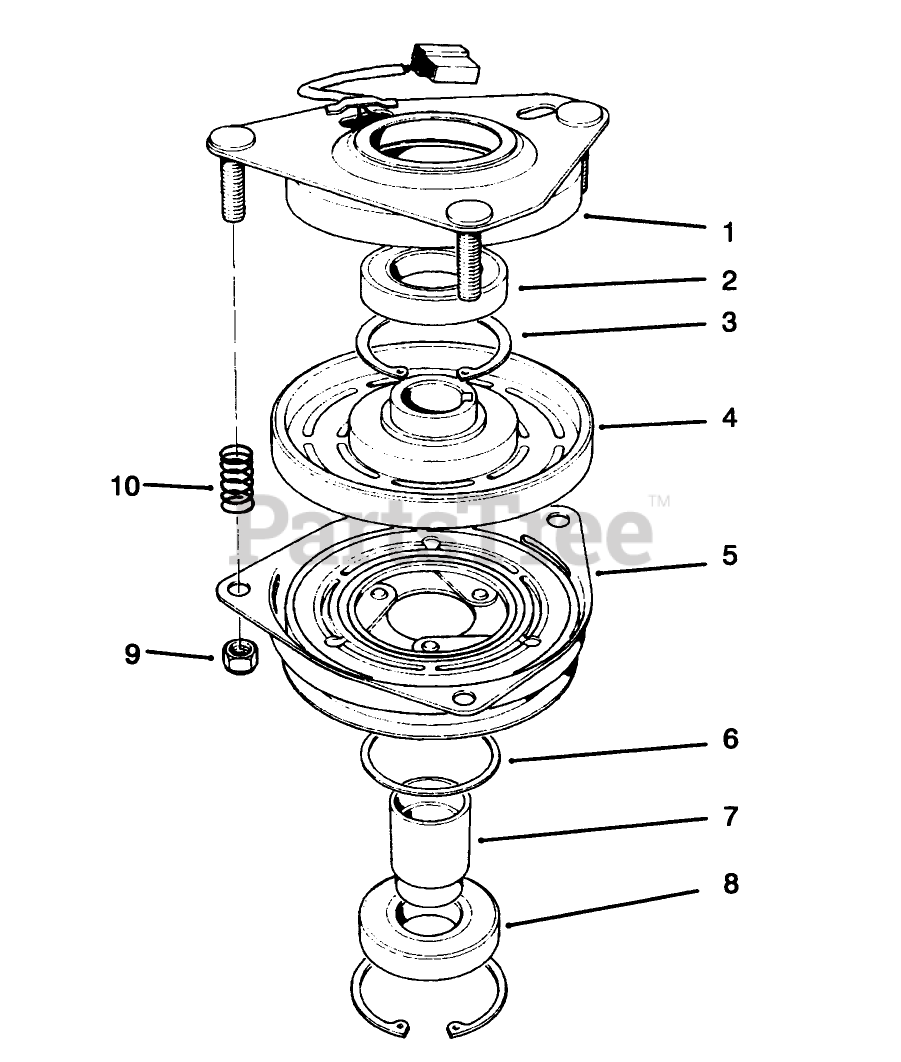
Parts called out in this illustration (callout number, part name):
1	FIELD BEARING ASM
2	BEARING-FIELD
3	RING-RETAINING
4	FIELD COIL/ROTOR BEARING ASM
6	SPACER-BEARING, PULLEY
7	COLLAR-BEARING
9	NUT-HEX
10	SPRING
